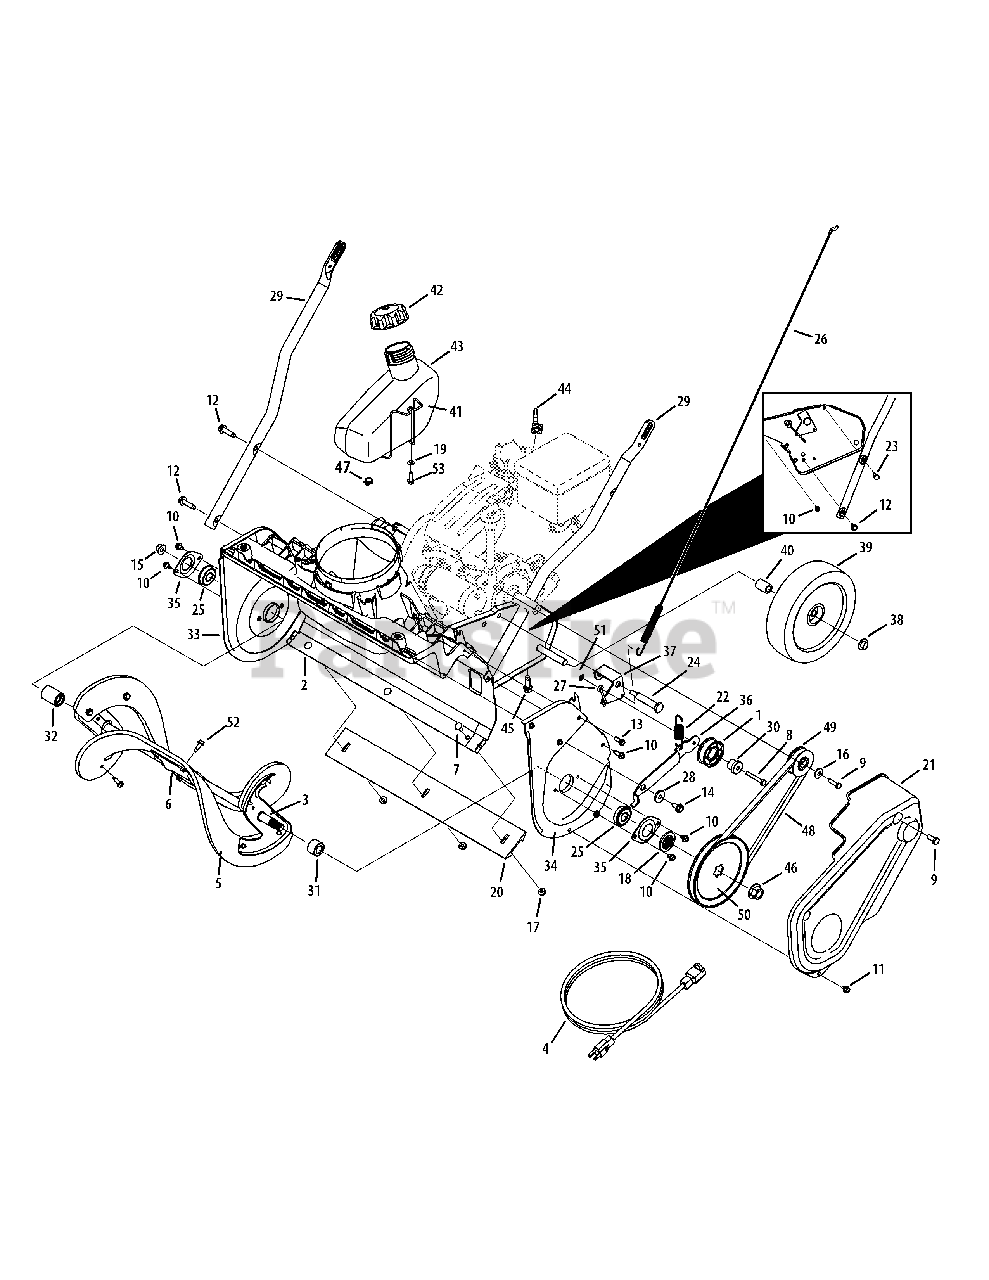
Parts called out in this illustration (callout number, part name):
1	Idler Pulley Assembly
3	Auger Assembly Complete
3	Auger Assembly Axle w/o paddles and center auger bracket
4	3-Prong Extension Cord
5	Auger Paddle Replacement Kit
6	Hex Washer Screw 1/4-20 x.750
7	Carriage Screw, 1/4-20 x .62
8	Hex Screw, 1/4-20 x 1.50
9	Hex Lock Screw, 5/16-24 x .750
10	Hex Washer Screw, 1/4-20 x .625
11	Hex Washer Screw, 1/4-20 x .500
12	Hex Washer Screw, 5/16-18 x 1.250
13	Hex Washer Screw, 1/4-15 x .750
14	Hex Washer Screw, 5/16-18 x .75
15	Flange Lock Nut, 3/8-16
16	Thrust Washer, .330 x 1.25 x .120
17	Flange Lock Nut, 1/4-20
18	Pulley Hub
19	Washer, .265 x 1.00 x .030
20	Shave Plate
21	Belt Cover
22	Extension Spring, .70 x 3.035
23	Hex Screw, 5/16-24 x 1.25
24	Shoulder Bolt, 5/16-24 x .496 x 2.18
25	Ball Bearing, .500 x 40mm x 12mm
26	Clutch Cable
27	Drive Cable Wire Support
28	Shoulder Spacer
30	Shoulder Spacer, .260 x .785 x .538
31	LH Auger Spacer
32	RH Auger Spacer
38	Push Cap, 1/2
39	Wheel, 8"
39	Wheel, 7"
40	Spacer, .525 x .775 x .835
41	Gas Tank Wire Support
42	Fuel Cap
43	Fuel Tank
44	Choke Extension Lever
45	Hex Washer Screw, 3/8-16 x 1.000
46	Flange Nut, 7/16-20
47	Hose Clamp
48	Belt, .500 x 35.06
49	Pulley Half, .625 x 2.25
50	Pulley, 1/2 x 6.00
51	Push Nut
52	Hex Washer Screw, 1/4-20 x .750
53	Screw, 1/4-10 x .625
